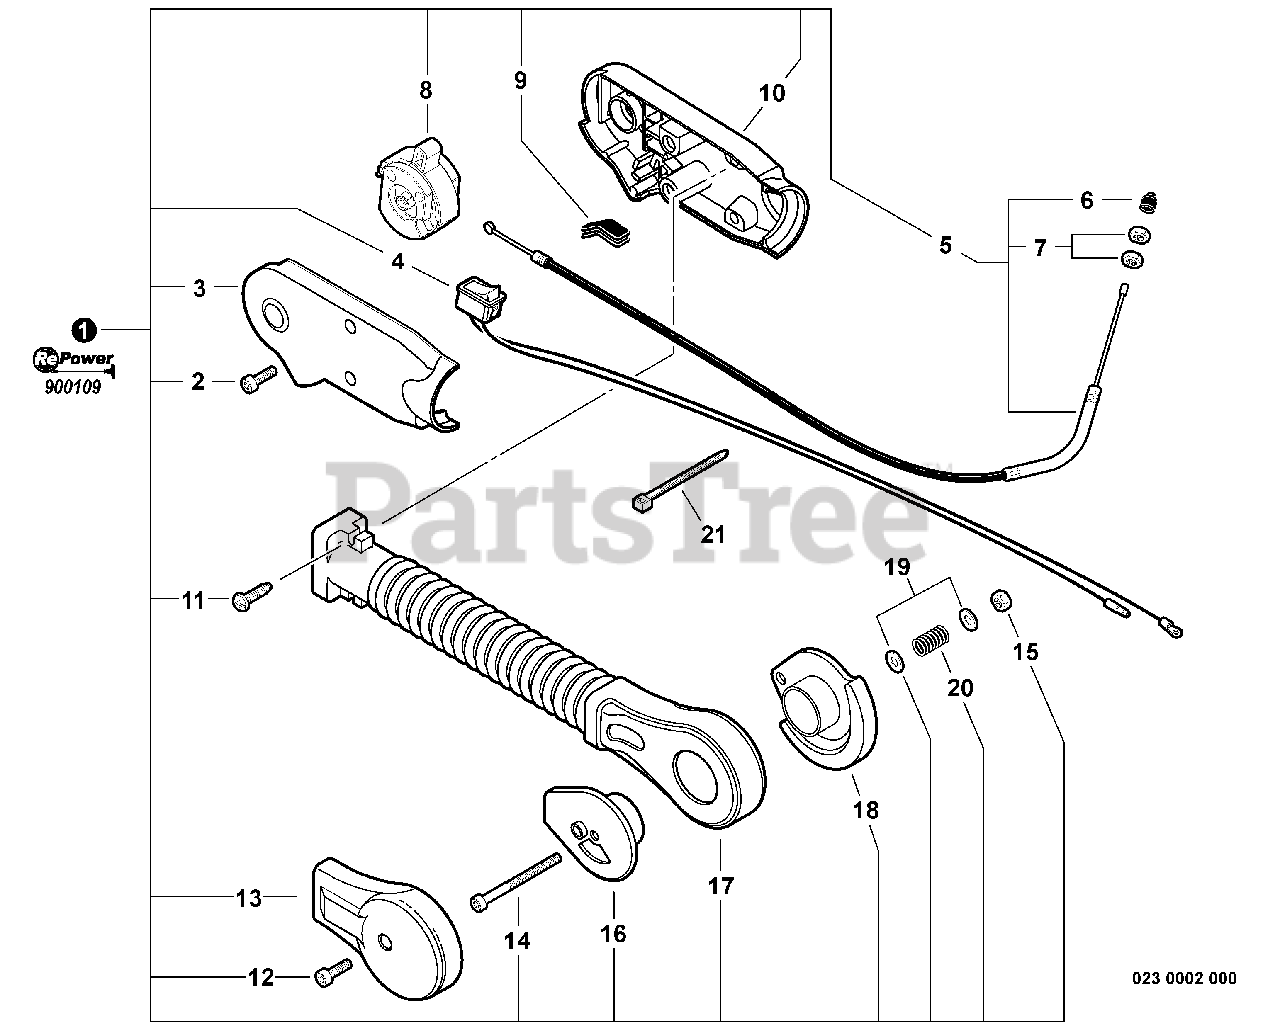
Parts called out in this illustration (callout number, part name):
1	THROTTLE CONTROL KIT - HIP MOUNT
2	BOLT 5×14
3	GRIP, LEFT THROTTLE
4	SWITCH, ON-OFF
5	CABLE ASSY, THROTTLE
6	CAP, DUST
7	NUT 6 MM
8	CONTROL, THROTTLE
9	GROMMET
10	GRIP, RIGHT THROTTLE
12	BOLT 5×14
13	BRACKET, ARM - OUTER
14	SCREW M5×80
15	NUT, LOCK M5
16	BRACKET, ARM - OUTER
17	ARM, THROTTLE CONTROL
18	BRACKET, ARM - INNER
19	WASHER 5.5×18×1
20	SPRING, COMPRESSION Ø9.53×24.13
21	STRAP, TIE
